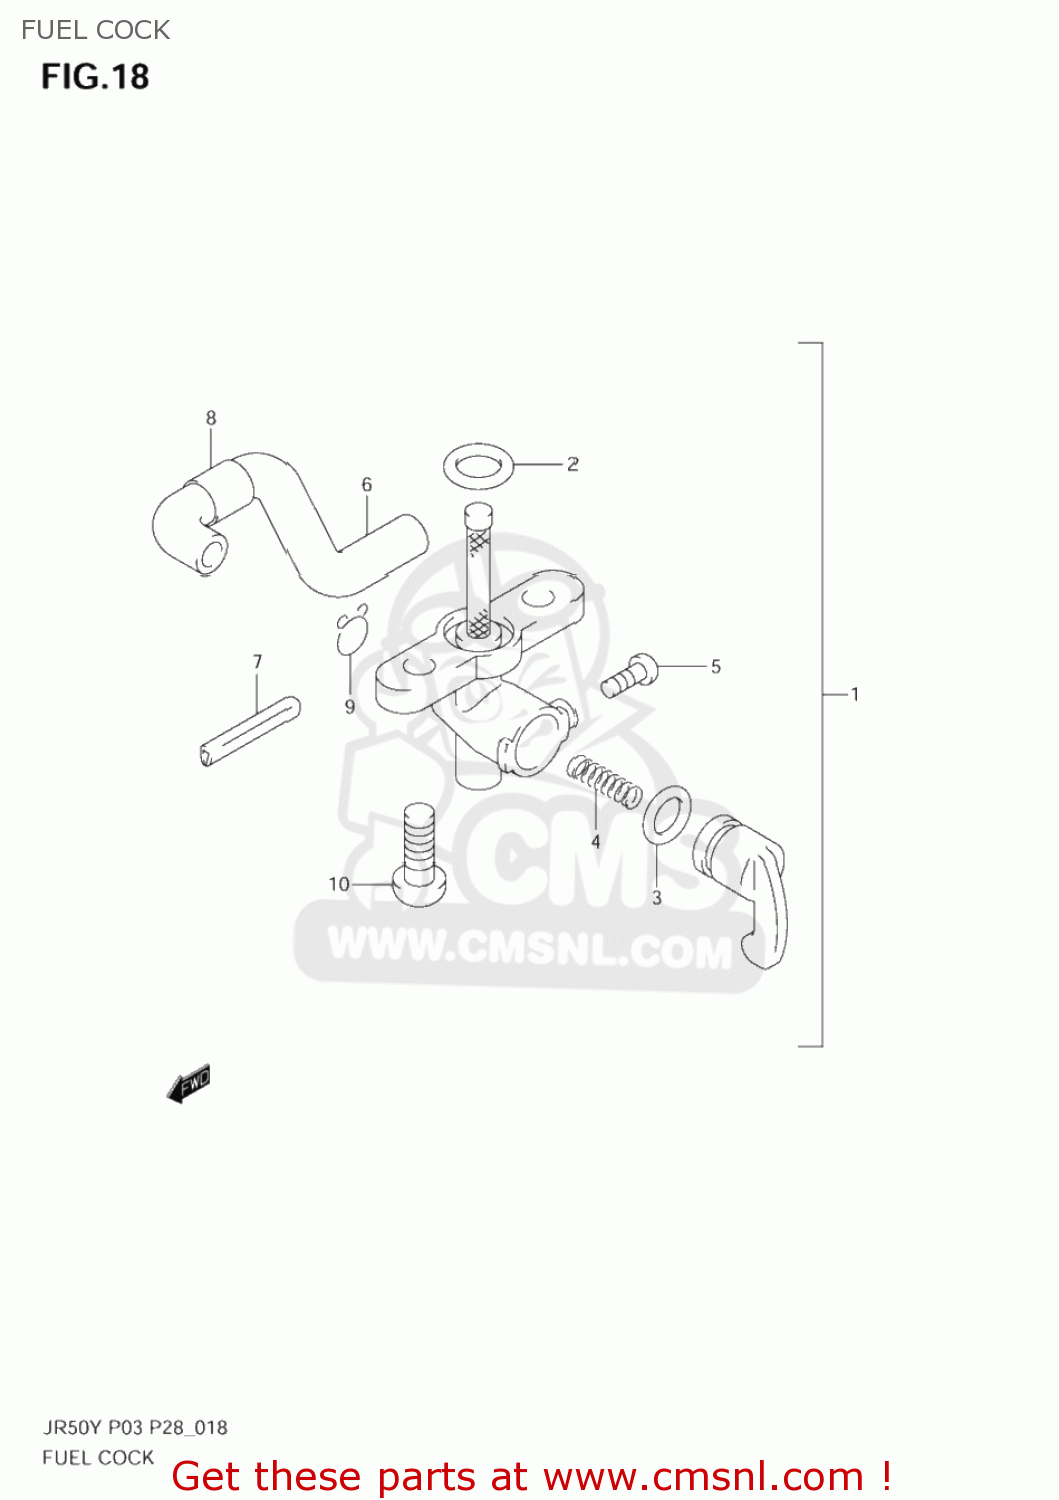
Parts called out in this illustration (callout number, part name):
1	COCK ASSY,FUEL
2	O RING
3	O RING,LEVER
4	SPRING
5	SCREW
6	HOSE,FUEL
7	PROTECTOR,NO.1
8	PROTECTOR(14.5X15.5X600)
9	CLIP
10	BOLT
